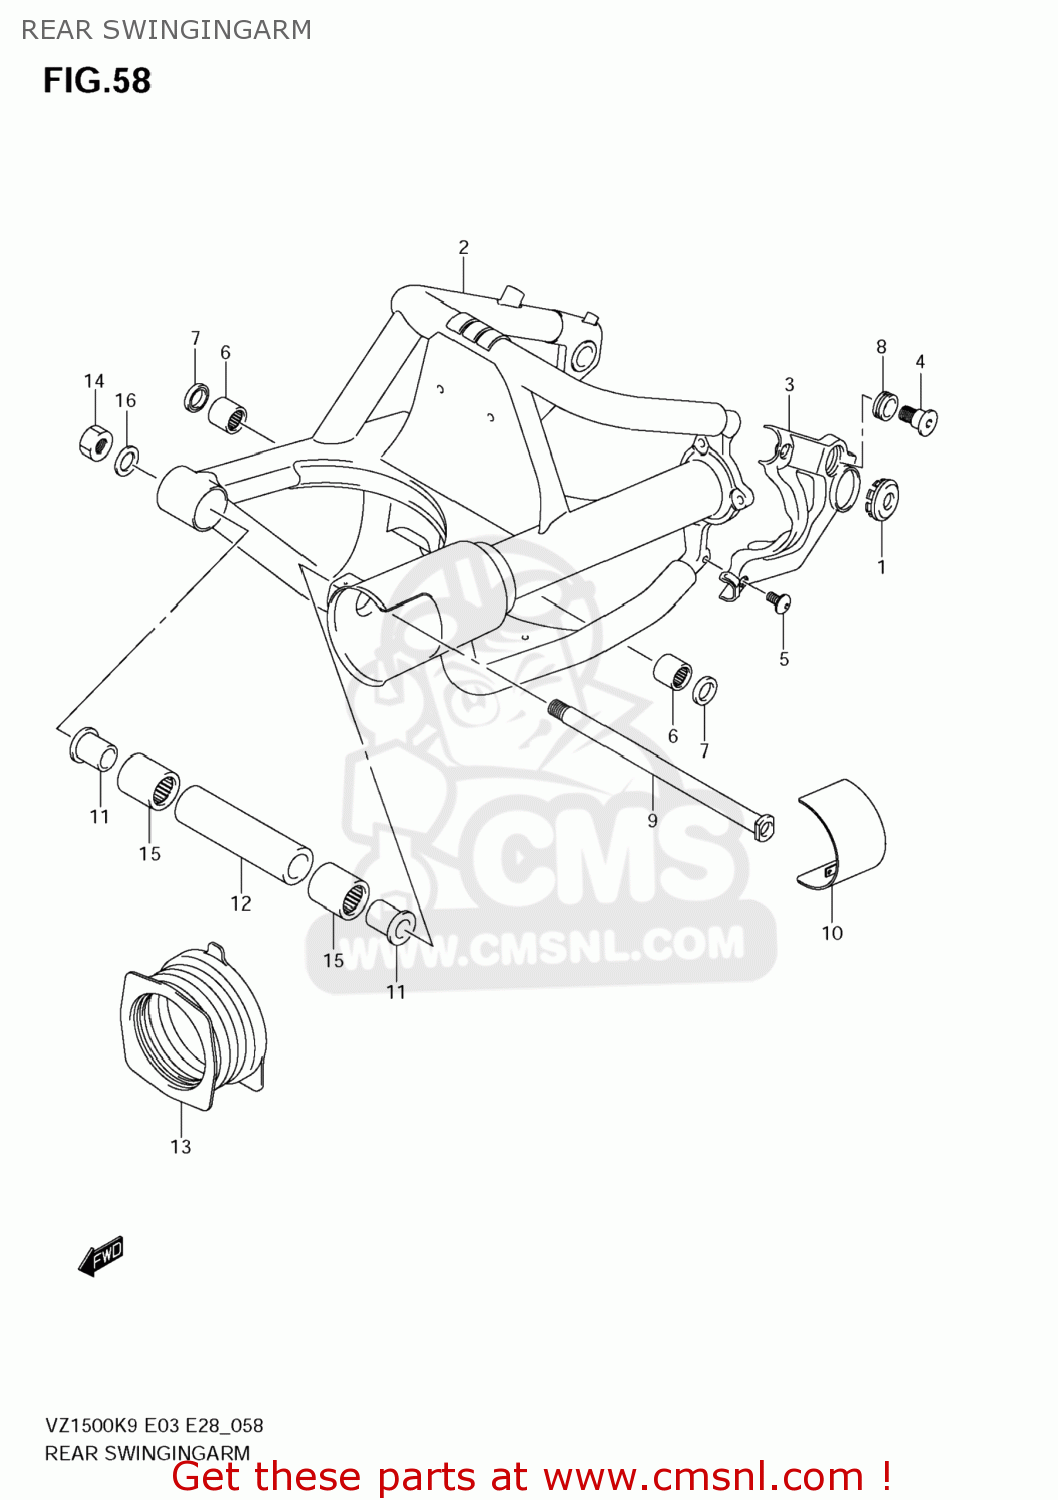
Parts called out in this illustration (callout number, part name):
1	CAP,FRAME PIVOT
2	SWINGINGARM,RE
3	COVER,RR SWINGINGARM,L(BLACK)
4	BOLT,RR SWGARM
5	SCREW(8X16)
6	BEARING(22X29X25)
7	SEAL,OIL(22X29X4)
8	CUSHION
9	SHAFT,RR SWINGINGARM PIVOT
10	COVER,RR SWGARM PIVOT,L
11	SPACER,RR SWGARM PIVOT BERRING
12	SPACER,RR SWGARM PIVOT CTR
13	BOOT,PROPELLER
14	NUT
15	BEARING(25X33X35)
16	WASHER
